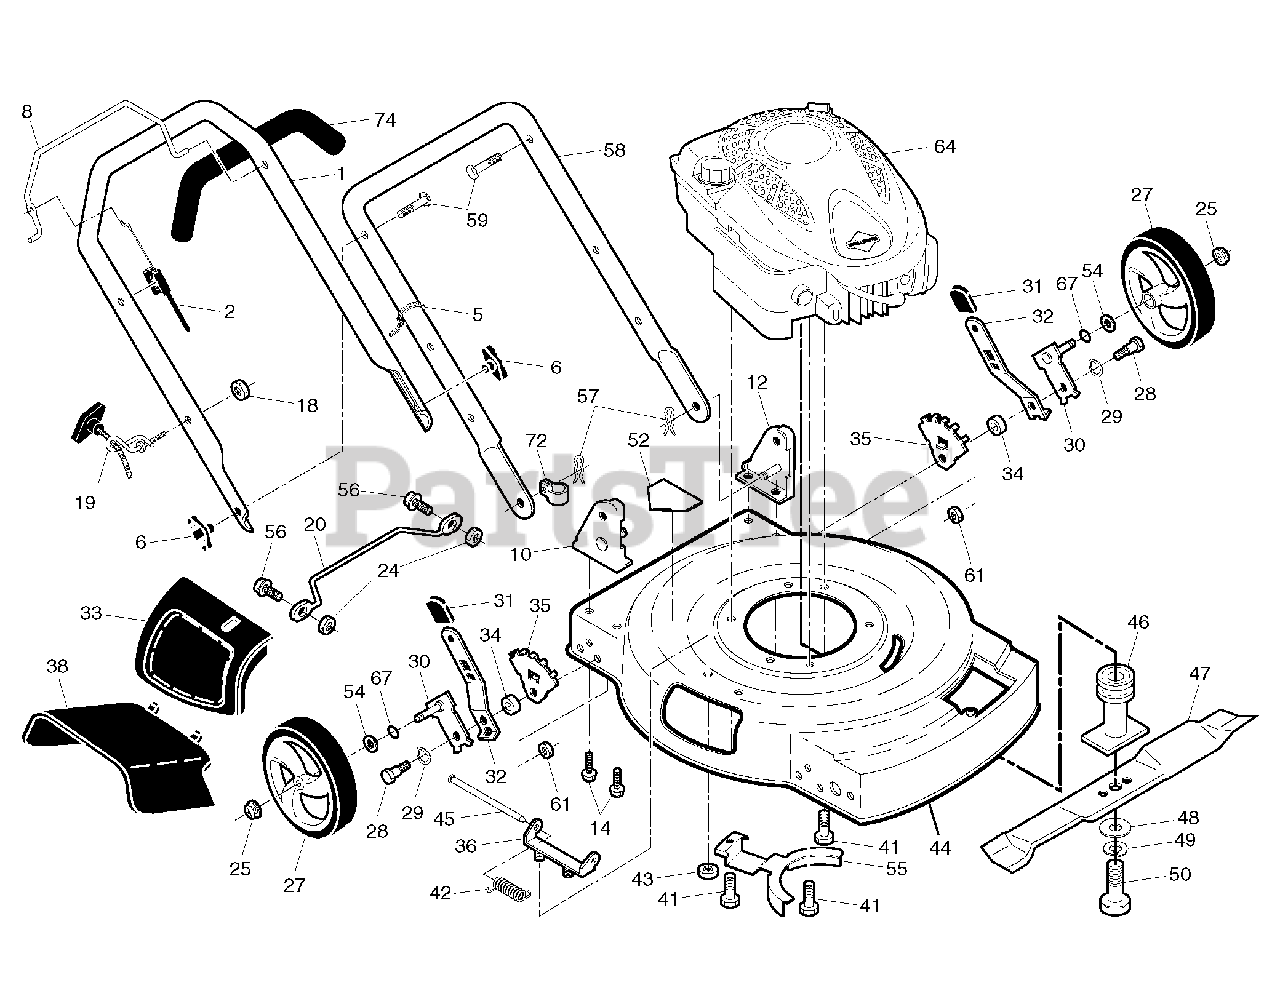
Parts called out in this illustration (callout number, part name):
2	CABLE.MZR
5	TIE GUIDE
6	KNOB, DEFLECTOR
10	HANDLE BRACKET ASM. RH
12	HANDLE BRACKET ASM. LH
14	SCREW 5/16-18
18	NUT
19	GUIDE.ROPE.STD.BLK.ZIN
25	NUT.HEX.FLANGE.3/8-16.LOCKNUT
28	BOLT SHOULDER 3/8 -16X1
29	WASHER FLAT
30	AXLE ARM ASSY.
31	SELECTOR KNOB
32	SPRING.SEL.EXT.21.DOMED.12/14
34	SPACER.HEIGHT.ADJUSTER
35	BRACKET.ADJ.WHEEL.5POS.ADS
36	HINGE BRACKET
41	BOLT 3/8-16X1-1/8
42	TORSION SPRING
43	LOCKNUT
45	ROD.HINGE.COMBI-C
46	ADAPTER.BLADE/PULLEY.25M
48	WASHER,HARDEN
49	LOCKWASHER
50	SCREW, HEX HD 3/8-24 X 1-3/8
52	DECAL.INTERNATIONL.CUTFINGER
54	WASHER PM
55	BRACKET.ENG/BELTKEEPER.BZP
57	HAIRPIN COTTER
59	BOLT, HANDLE 5/16-18X1.75
61	LOCKNUT
67	O-RING..070X.487.NEOPRENE
72	CLIP.CABLE.BLK
74	GRIP.HANDLE.FOAM
